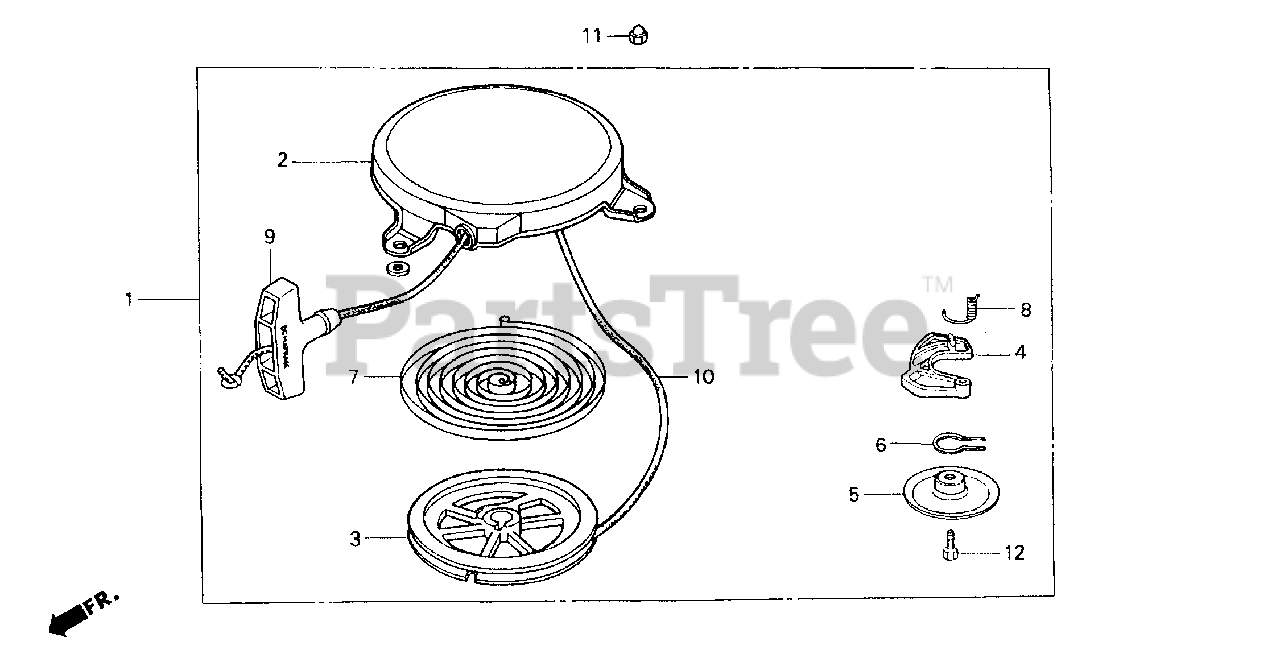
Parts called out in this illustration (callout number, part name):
1	STARTER ASSY., RECOIL
2	CASE, RECOIL STARTER
3	REEL, RECOIL STARTER
4	RATCHET, STARTER
5	PLATE, FRICTION
6	SPRING, FRICTION
7	SPRING, RECOIL STARTER
8	SPRING, RETURN
9	KNOB, STARTER
10	ROPE, RECOIL STARTER (#4X65") (NA USE ALT:08540-ZG921-11)
11	NUT, CAP (6MM)
12	BOLT, HEX. (6X20)
